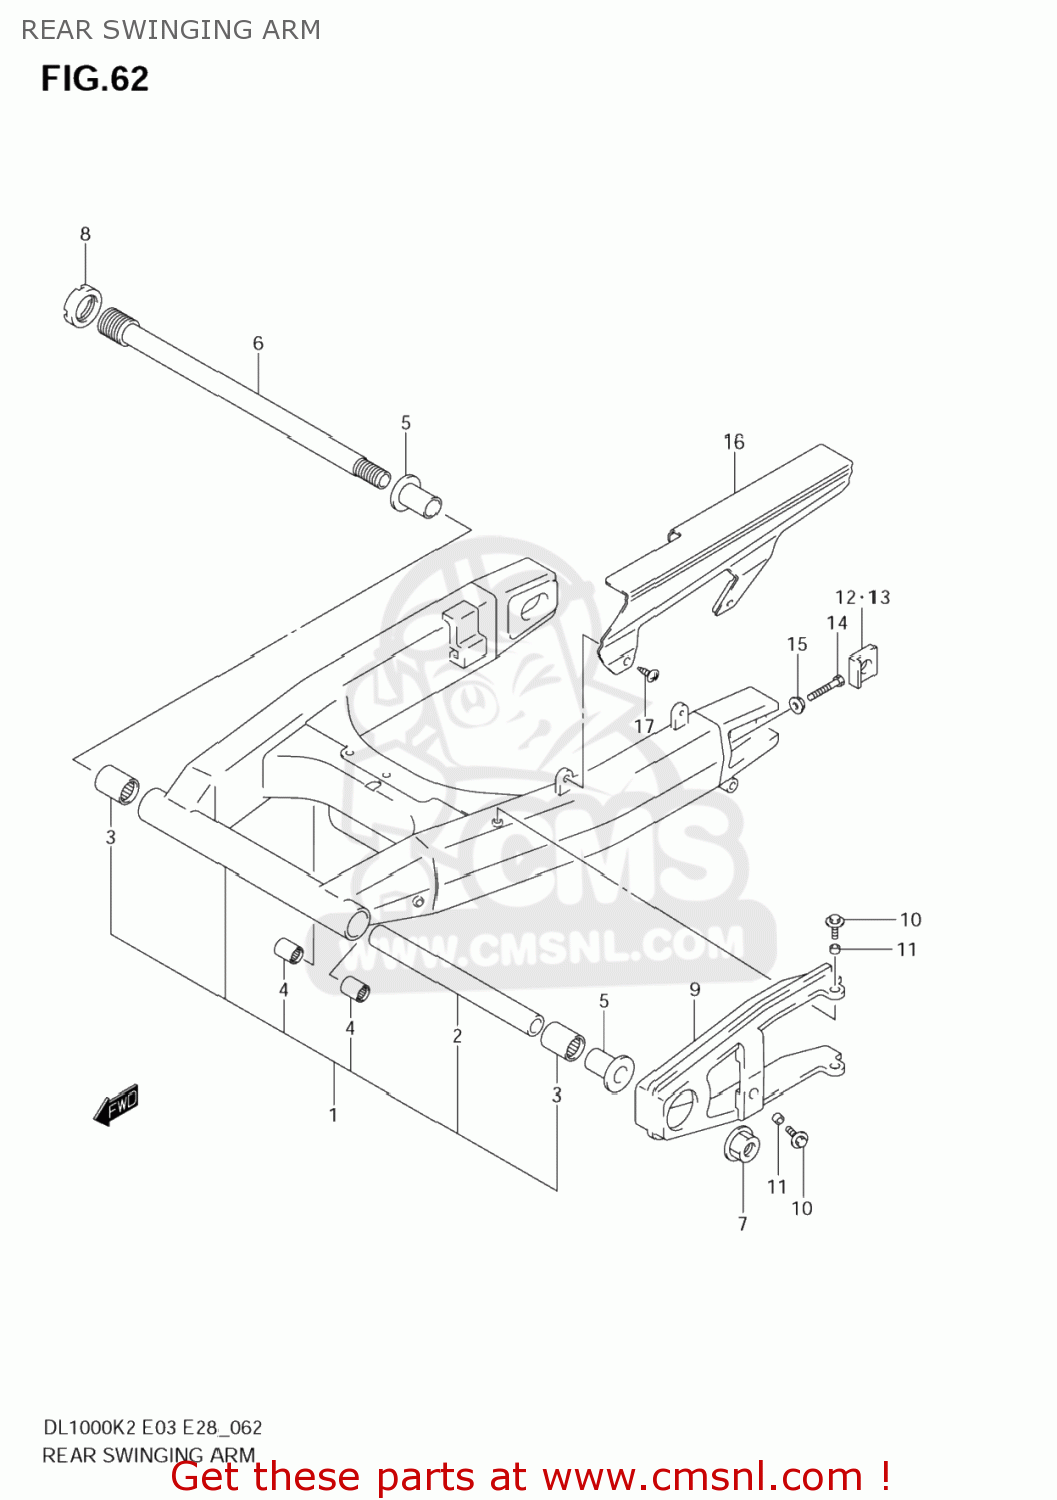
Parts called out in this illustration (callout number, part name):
1	SWINGING ARM ASSY, REAR
2	SPACER(20.8X27.2X196.7)
3	BEARING(25X33X35)
4	BEARING(17X24X25)
5	SPACER,RR SWGARM PIVOT BERRING
6	SHAFT,RR SWINGINGARM PIVOT
7	NUT,REAR SWING ARM PIVOT BOLT
8	NUT ,18MM
9	BUFFER,CHAIN TOUCH DEFENSE
10	BOLT(6X20)
11	SPACER(6.5X9X5)
12	WASHER,CHAIN ADJUSTER
13	WASHER,CHAIN ADJUSTER
14	BOLT(8X50)
15	NUT
16	CASE,CHAIN
17	SCREW(6X16)
